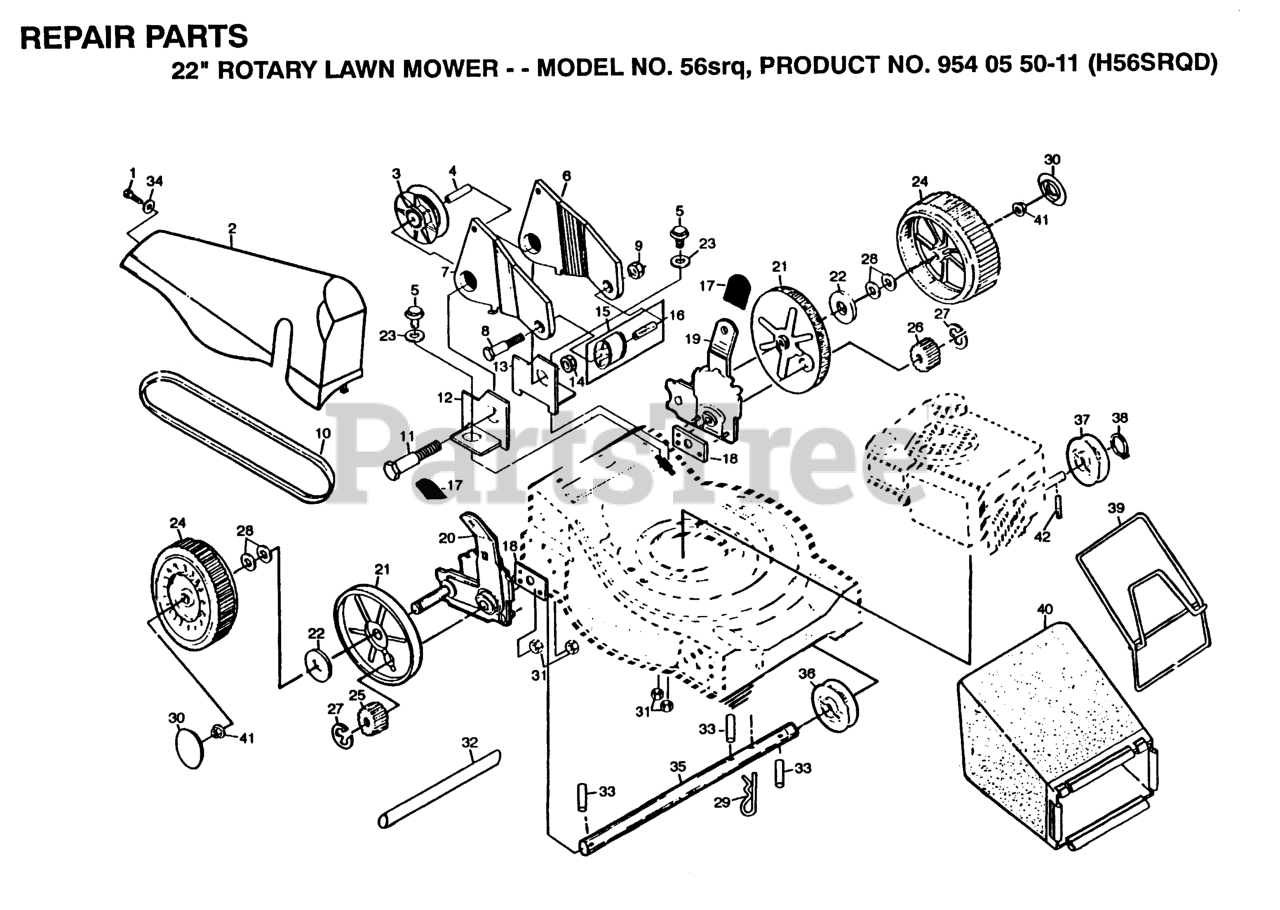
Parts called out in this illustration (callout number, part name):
1	TAPPING SCREW
2	DRIVE COVER
4	PULLEY SPACER
8	HEX BOLT
11	BOLT
14	LOCKNUT
16	IDLER SPACER
21	DUST SHROUD PM
22	WASHER FLUT
24	WHEEL&TIRE ASS'Y
25	DR PINION RH
26	DR PINION LH
27	E-RING
29	RETAINER CLIP PM
31	NUT
32	DR SHAFT CVR NLA
33	DRIVE PAWL
36	DRIVE PULLEY PM
38	RETAINING RING ST
39	CATCHER FRAME
40	GRASS BAG
41	DOWEL PIN
